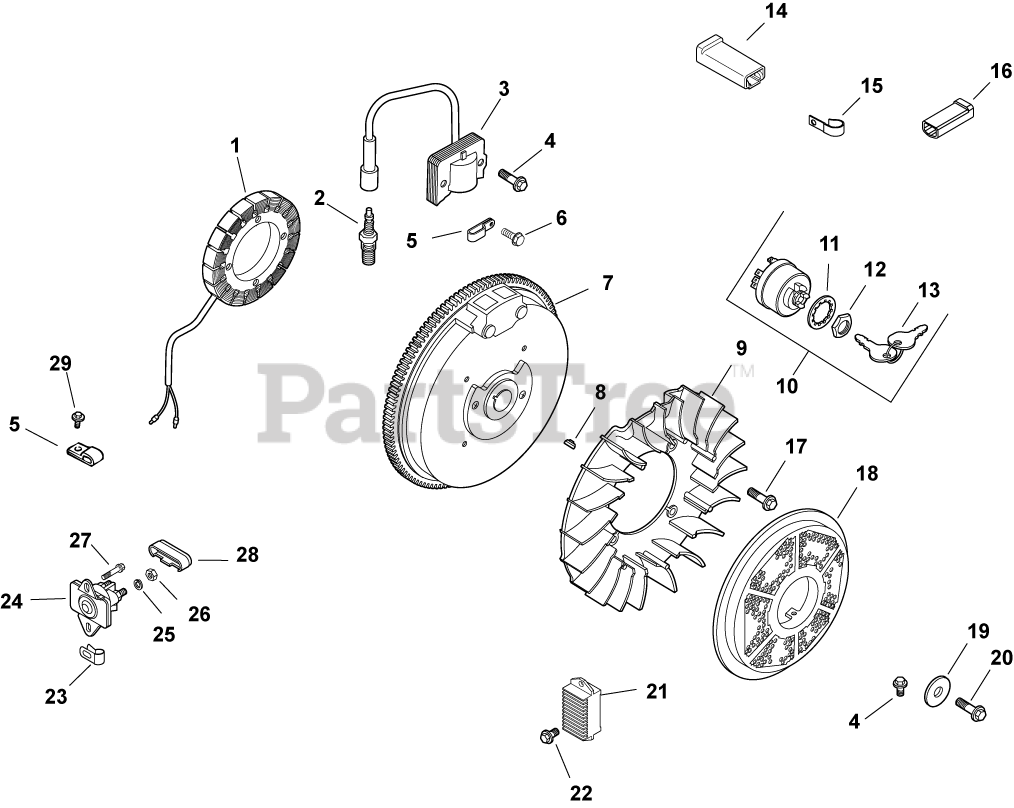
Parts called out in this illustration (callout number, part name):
1	KIT, 25 AMP STATOR ASSY.
2	PLUG, SPARK (STD)
3	MODULE, IGNITION
4	SCREW, FLG THD FRM M5X.8X20-(#25086399S)
6	SCREW, FLG THD FRM M5X.8X10
8	KEY, 3/16" X 5/8"
9	FAN - DISCONTINUED
10	SWITCH ASSY, KEY (KM)-USE 25 099 32-S
11	WASHER, INTERNAL TOOTH
12	NUT, KEY SWITCH
13	KEY, SET -USE 48 340 01-S
14	CONNECTOR
15	CLIP, CABLE
16	CONNECTOR (1 CONTACT)
17	BOLT, SHOULDER
19	WASHER, FLAT 13/32"
20	SCREW, FLG M10X1.5X45 - (#25086361S)
21	REG/RECTIFIER (20/25 AMP)-USE 25 403 20-
22	SCREW, FLG M6X1.0X16
24	SOLENOID - WATERPROOF (KM)-USE 25 435 08
25	WASHER, INT TOOTH LOCK 1/4"
26	NUT, JAM 1/4-20 GRADE 2
27	SCREW,FLG THD FRM M6X1.0X16-(#25086397S)
28	CAP, SOLENOID - DISCONTINUED
29	SCREW, THD FROM M5X0.8X30
